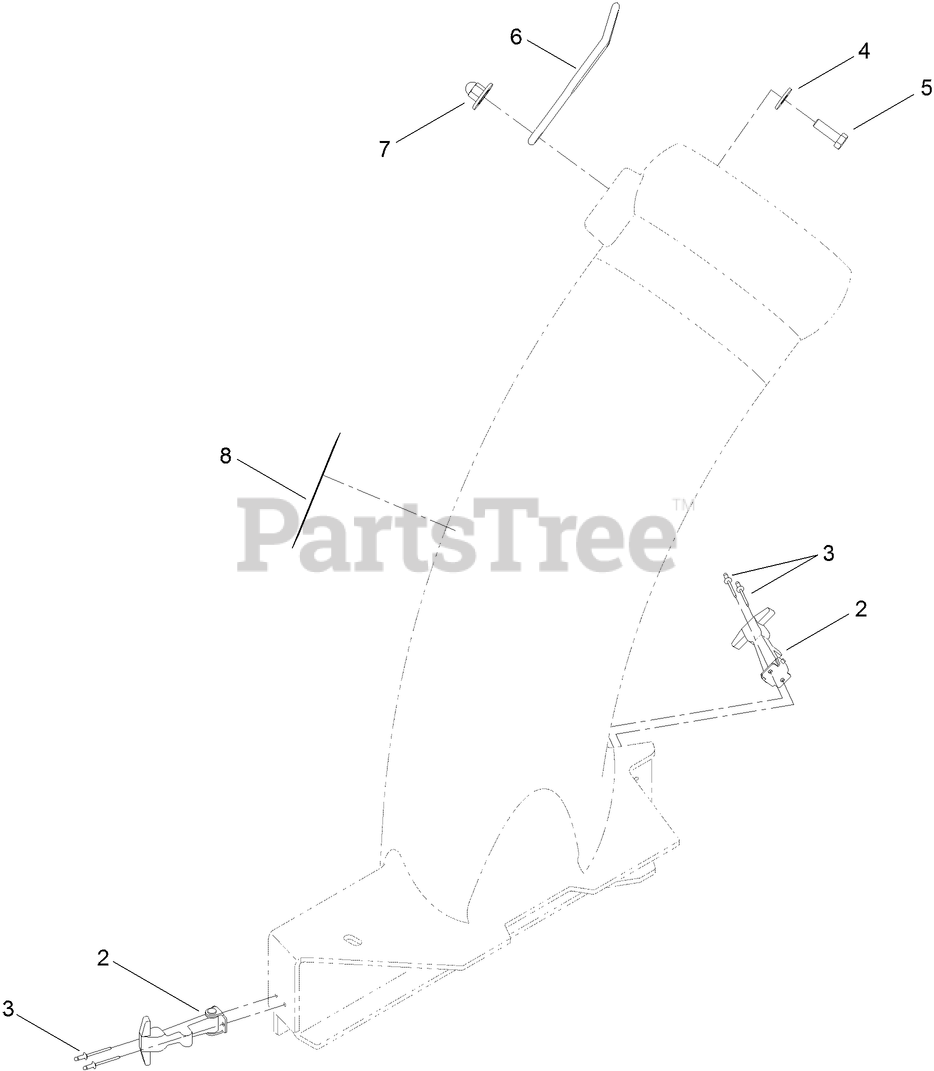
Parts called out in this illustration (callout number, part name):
2	HANDLE ASM
3	RIVET-POP
4	WASHER-FLAT
5	SCREW-HH
6	RETAINER-DUCT
7	NUT-IMPELLER
8	DECAL-DANGER
